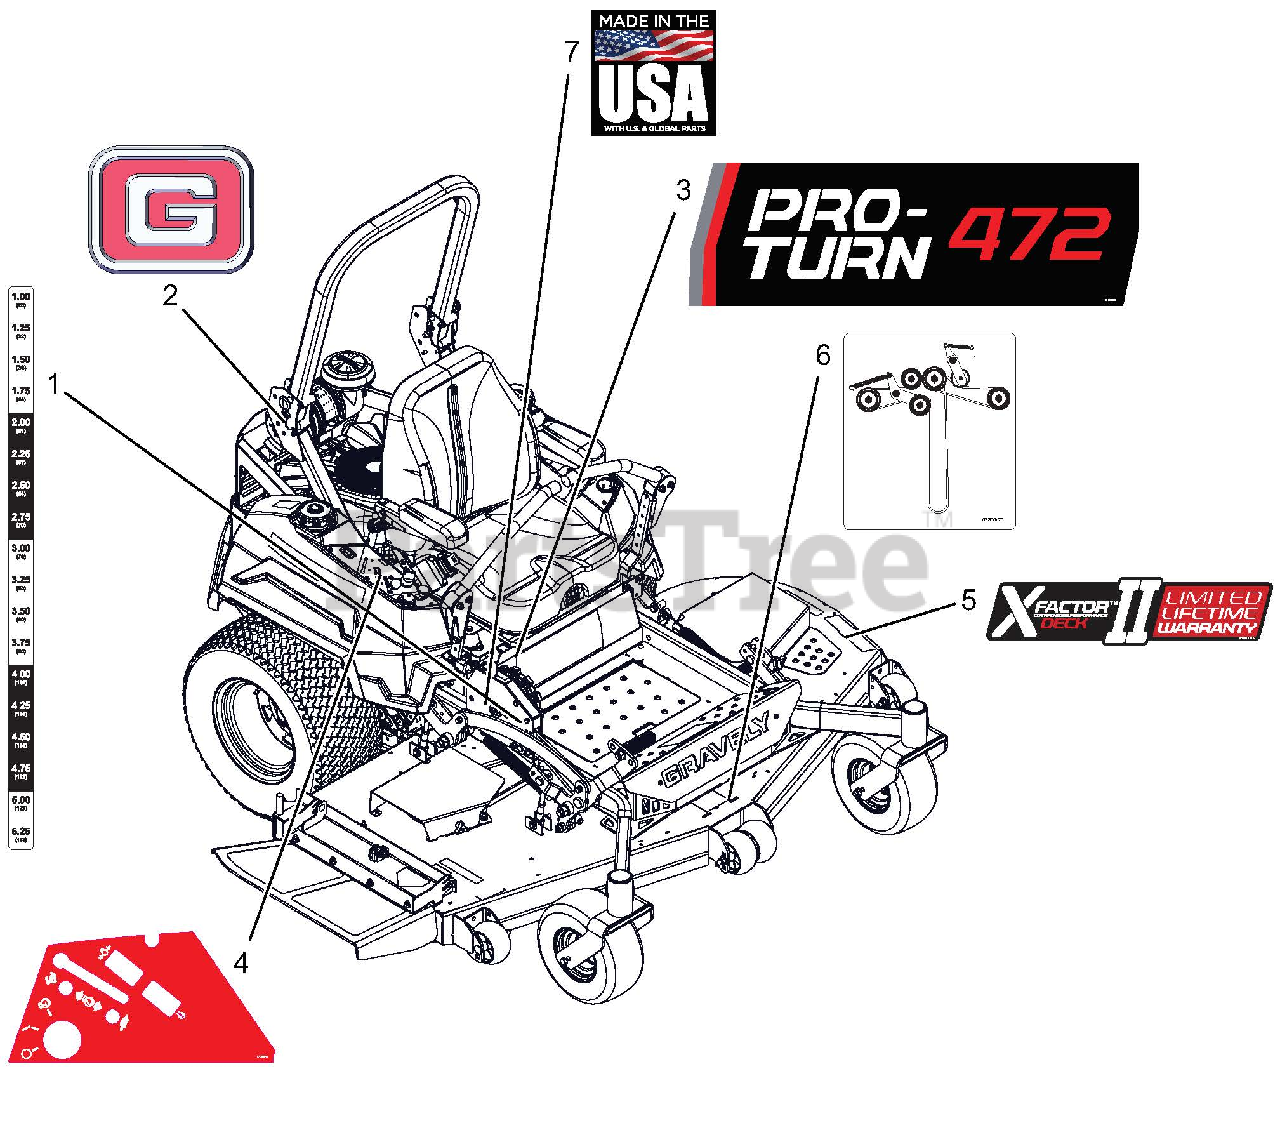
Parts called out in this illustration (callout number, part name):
1	DECAL, PT400 HEIGHT OF CUT
2	DECAL, GRAVELY BRAND
3	DECAL, PRO-TURN 472
4	DECAL, EFI CONTROL PANEL
5	DECAL, X-FACTOR DECK
6	DCL,BELT ROUTE-RH BK-SIDE IDLR
7	DECAL, MADE IN USA
